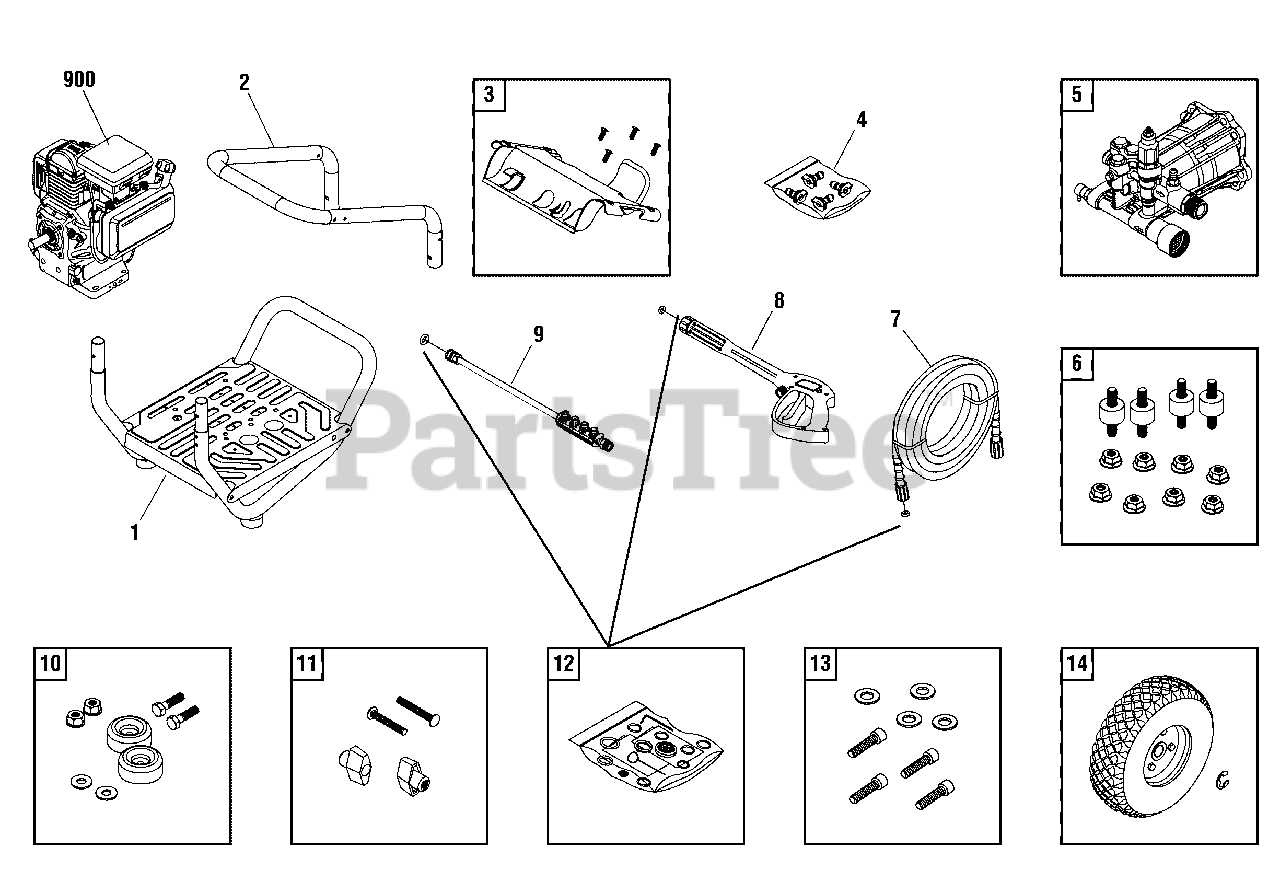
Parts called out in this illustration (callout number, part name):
4	KIT, QC Nozzles
6	KIT, Vibration Mount
7	HOSE
8	GUN
9	EXTENSION, QC
10	MOUNT, Vibration
11	KIT, Hardware, Handle
12	KIT, O-Ring
13	KIT, Hardware, Pump Mounting
900	* ENGINE
